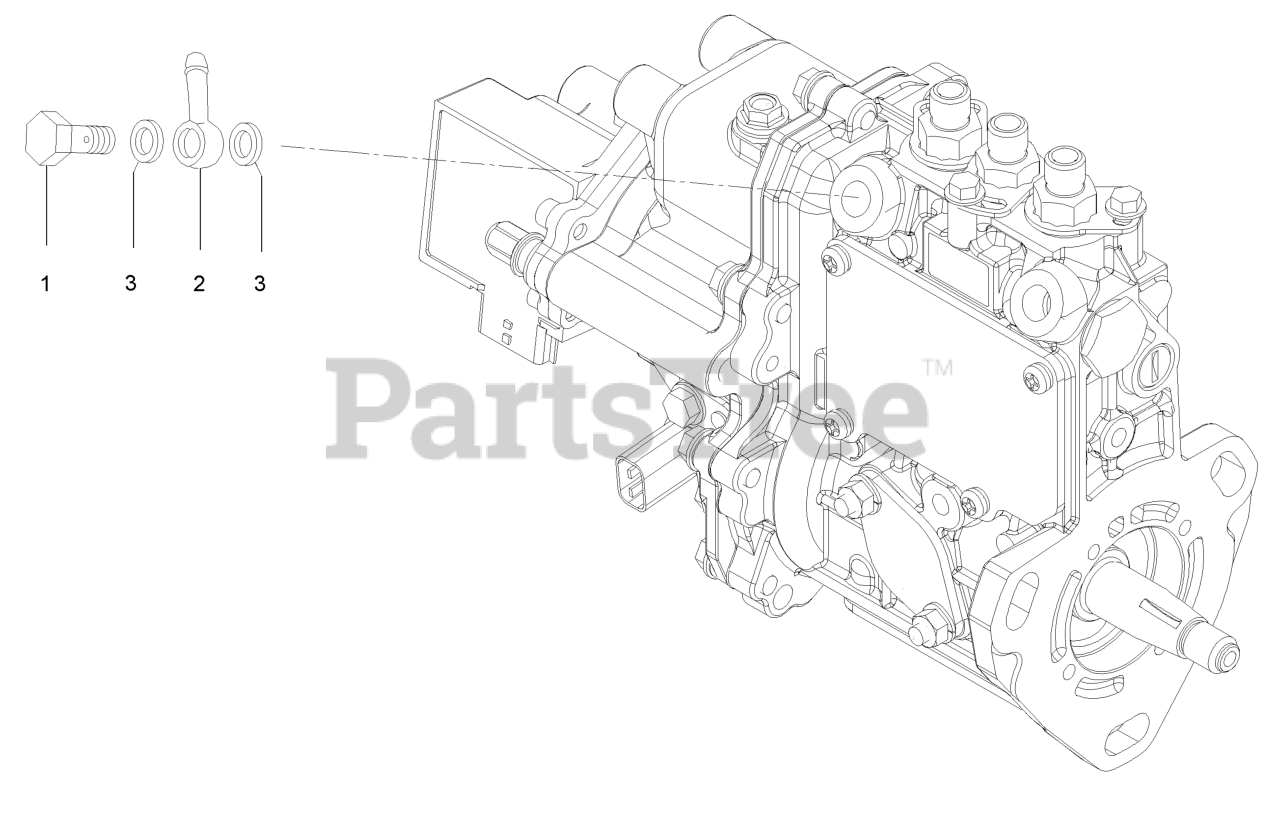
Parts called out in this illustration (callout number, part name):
1	Bolt-Pipe Joint
2	Joint-Pipe
3	Washer-Seal
